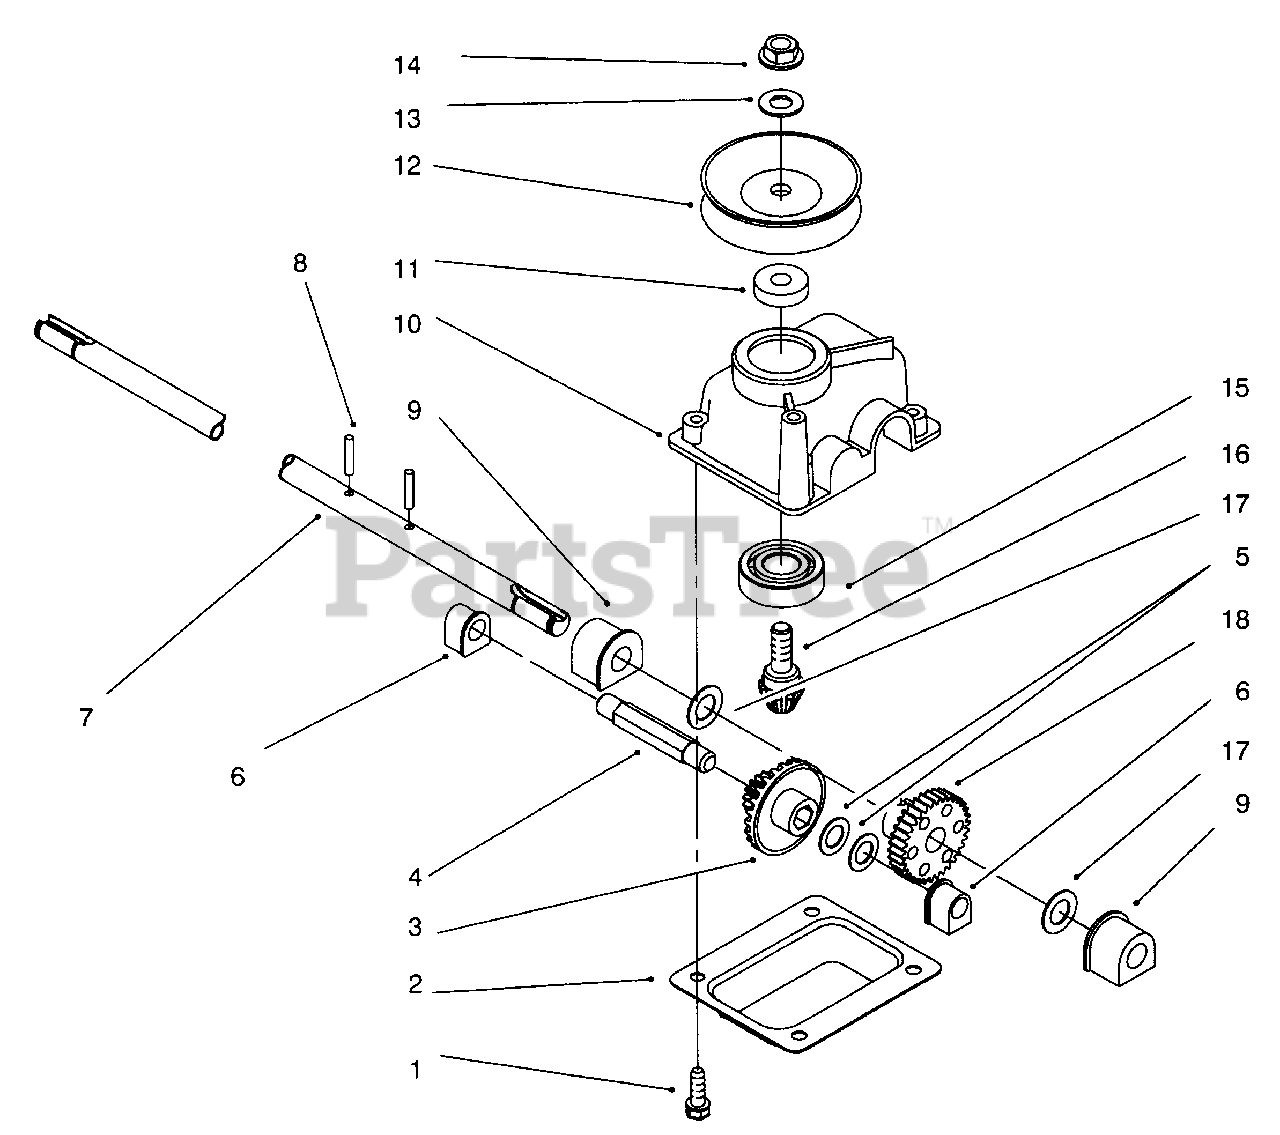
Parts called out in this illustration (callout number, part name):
1	Screw-Taptite
2	Cover-Gear Case
3	Pinion-15 Tooth
4	Shaft-Intermediate
7	Shaft-Output
8	Pin-Groove
9	Bushing-Output
10	Gearcase
12	Pulley-Half
15	Bearing-Ball
16	Gear-Bevel Pinion
17	Washer-Thrust
18	Gear 34 Tooth
